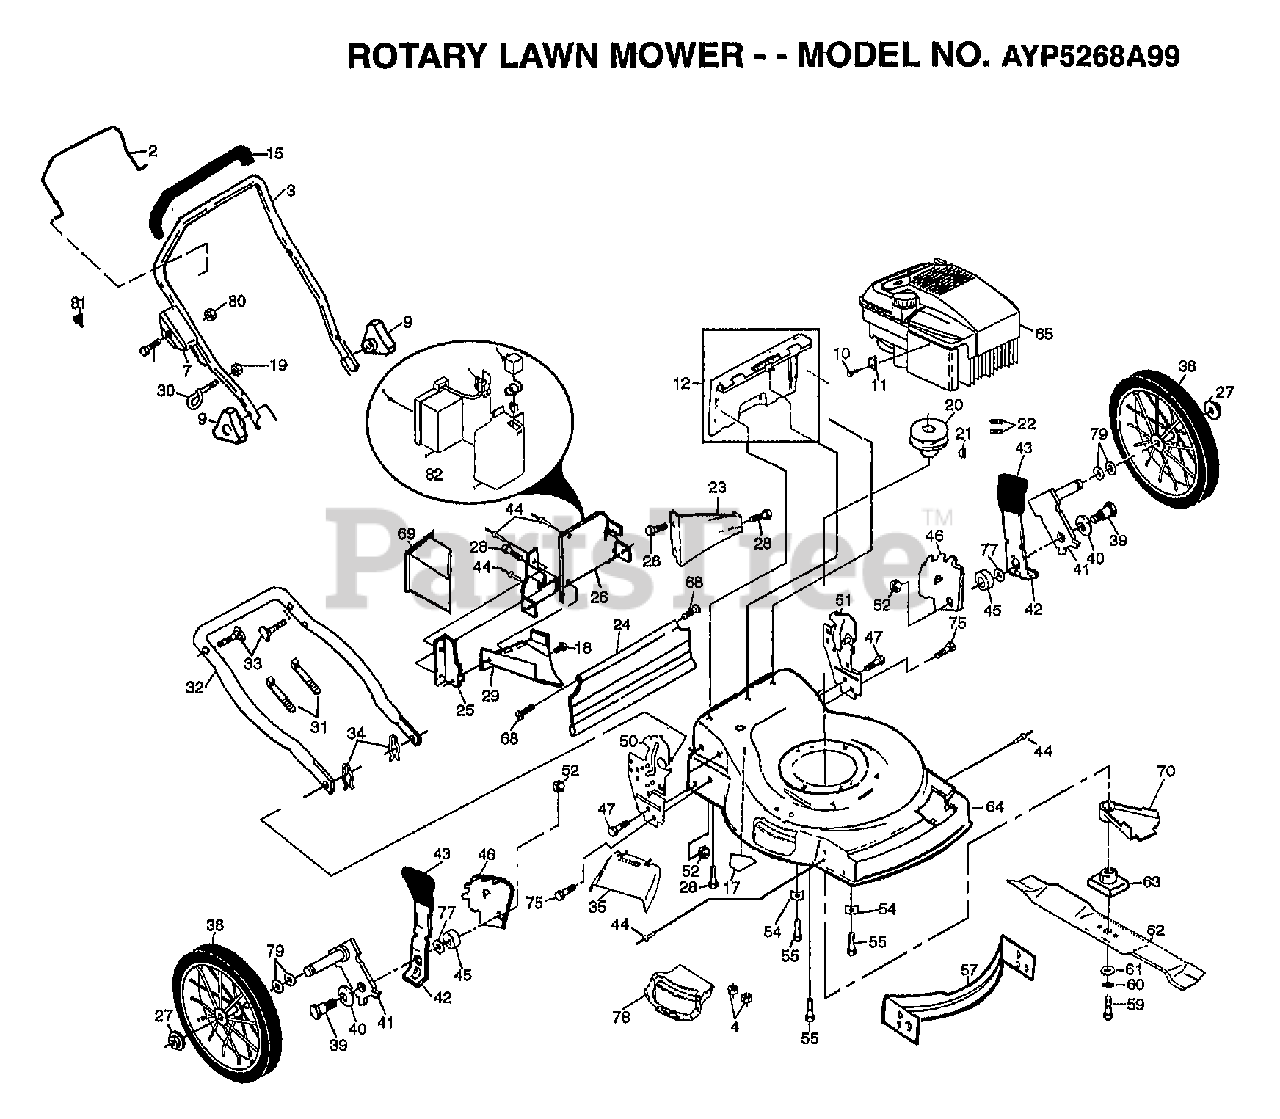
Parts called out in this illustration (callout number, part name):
2	BAIL.CNTRL.SRD.CM
3	HANDLE.UPPER.STD.
7	COMBI-KEY CONTROL
8	SCREW.HXHD.WASH.
9	KNOB PM
10	SCREW PM
11	CABLE CLAMP
12	KIT.DOOR.REAR
15	GRIP.HANDLE.FOAM
17	DECAL-DANGER PM
18	SCREW.HXTAP.10-24
20	ENGINE.PULLEY.FWG
21	HI PRO KEY PM
22	SCREW
23	REAR BAFFLE
24	SKIRT.REAR.FGD.22
27	HEX FLANGE LOCKNT
28	SCREW
29	DISCHARGE BAFFLE
30	ROPE GUIDE
32	HANDLE LOWER
33	BOLT.HANDLE.LM
34	HAIRPIN COTTER
35	GUARD.DISCH.CLIPO
38	ASM WHL & TIRE
39	BOLT SHLD 3/8-16
41	ARM.ASM.AXLE
42	SPRING SELECTOR
43	KNOB PM
44	BLIND RIVET
45	SPACER.HEIGHT.ADJ
46	BRACKET.ADJ.9POS.
47	SCREW.HXWS.5/16
50	HANDLE BRKT ASY R
51	HANDLE BRKT ASY L
52	LOCKNUT PM
55	BOLT.ENG.3/8-16
57	KIT.BAF.FRT.22RD
59	SCREW
60	LOCKWASHER
61	"WASHER,HARDEN"
62	"BLADE.MULCH.22"""
63	ADAPTOR.BLADE.LM
64	LAWNMOWER HOUSING KIT
68	HINGE SCREW
69	PLUG.MULCH.22RD
77	WASHER PM
78	KIT.DOOR.MUL.CO
79	WAVE WASHER
80	LOCKNUT
81	KEY
82	CHARGER PM
